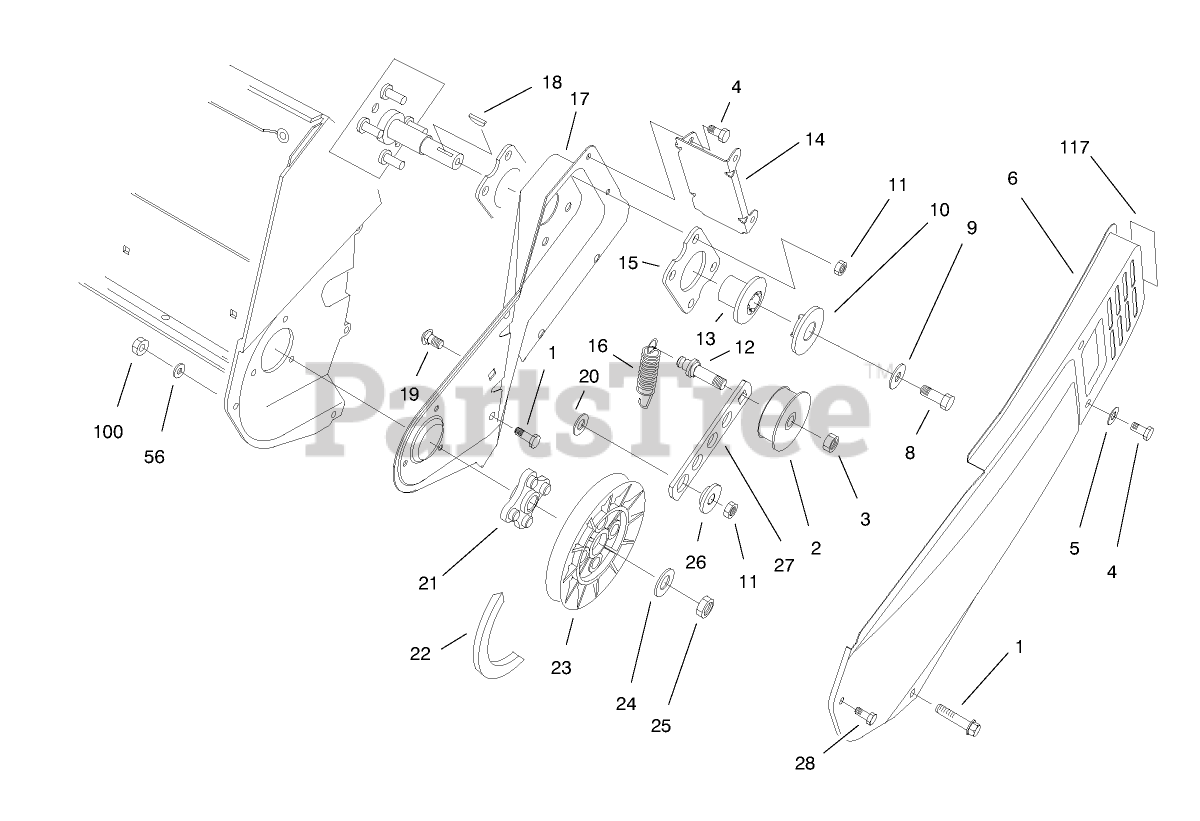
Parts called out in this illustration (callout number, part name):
1	SCREW-PLASTIC
2	PULLEY-IDLER
4	SCREW-HWH
5	WASHER-FLAT
8	SCREW-HH
9	WASHER-FLAT
10	CAP-HALF SHEAVE
11	NUT-LOCK, NI
12	PIN-IDLER
13	HUB-HALF SHEAVE
16	SPRING-EXTENSION
18	KEY-WOODRUFF
19	SCREW-CARR
20	WASHER
22	V-BELT
23	PULLEY-DRIVEN
24	WASHER-FLAT
25	NUT-LOCK, NI
26	BUSHING-IDLER
27	ARM-IDLER
56	WASHER-FLAT
100	NUT-LOCK, NI
117	DECAL-HOT
